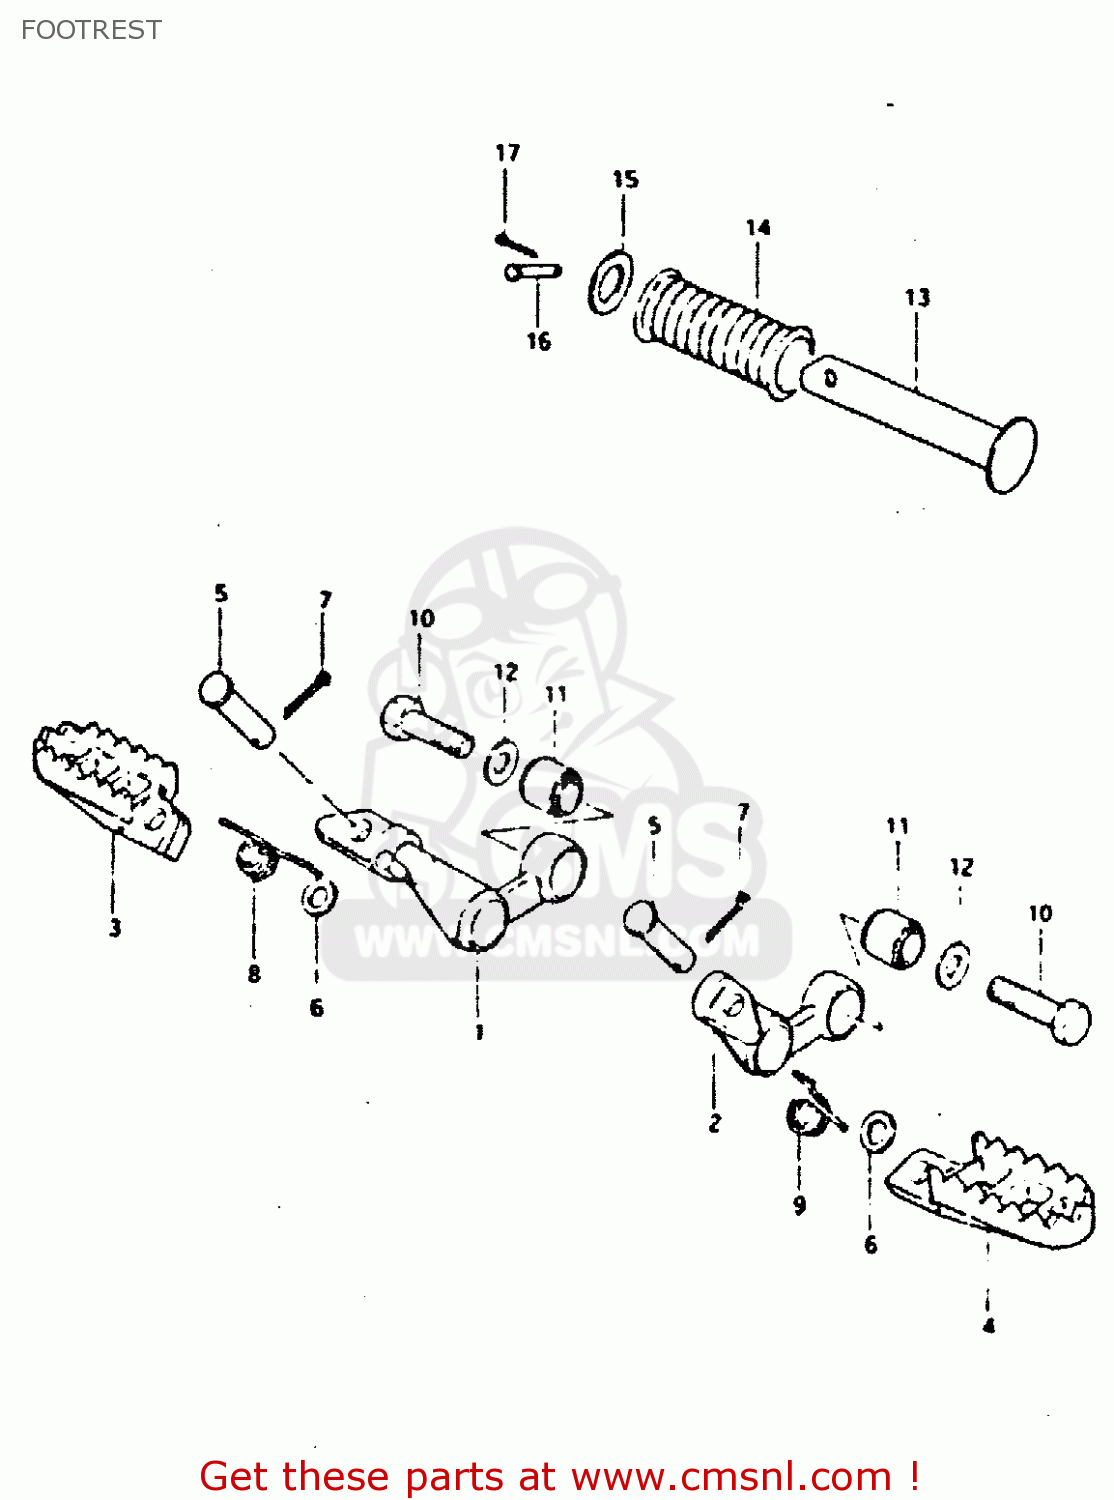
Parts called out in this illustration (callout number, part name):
1	BAR,FRONT FOOTREST
2	BAR,FRONT FOOTREST,LEFT
3	FOOTREST,RIGHT
4	FOOTREST
5	PIN
6	WASHER
7	PIN 30X20
8	SPRING
9	SPRING
10	BOLT
11	BUSH
12	WASHER (10.1X21X2.3)
13	BAR,FOOTREST RUBBER
14	RUBBER,PILLION FOOTREST
15	WASHER (19.5X32X2)
16	PIN
17	PIN 20X20
